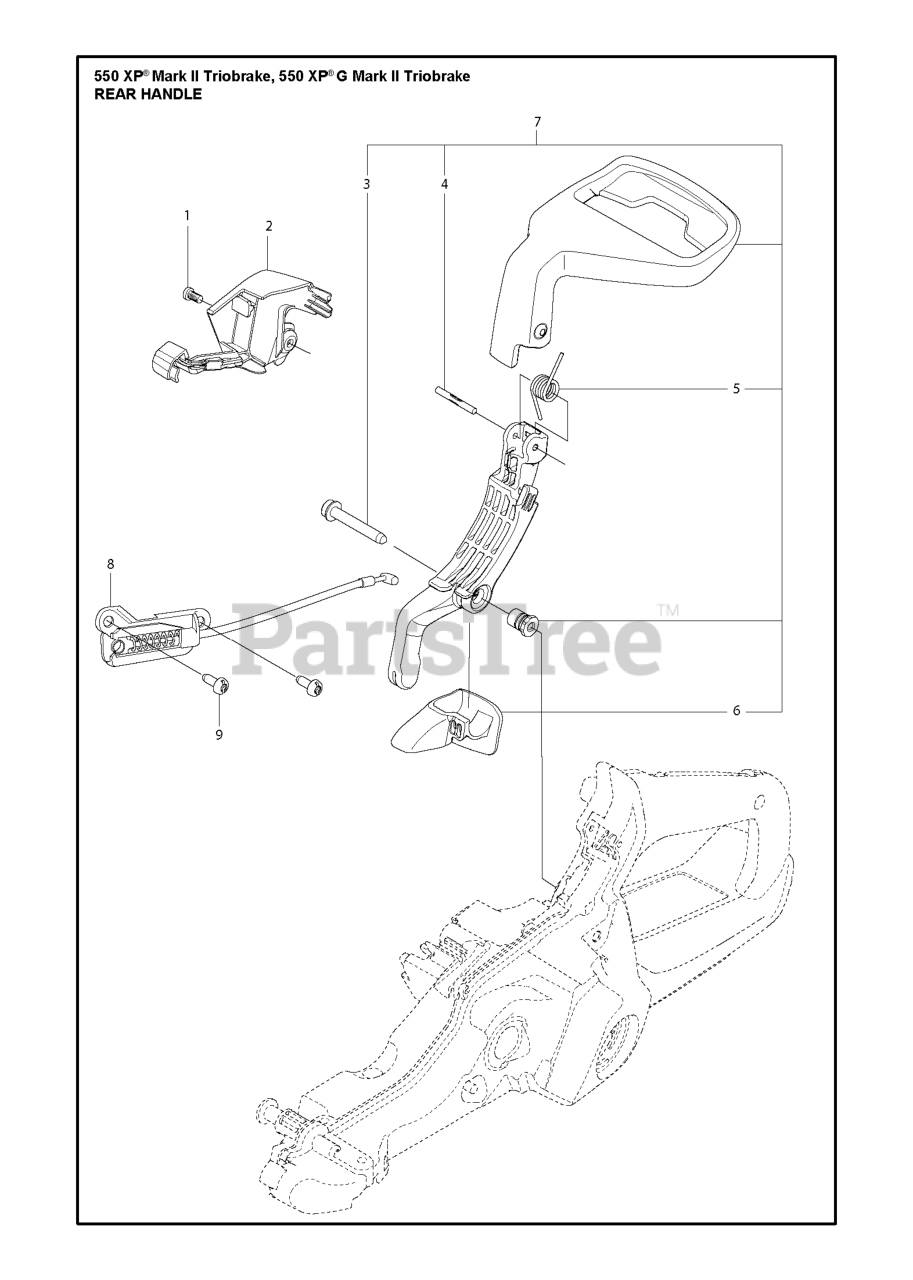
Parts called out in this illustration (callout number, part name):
1	SCREW CITXPANT
4	GROOVED PIN
7	HAND GUARD ASSY
